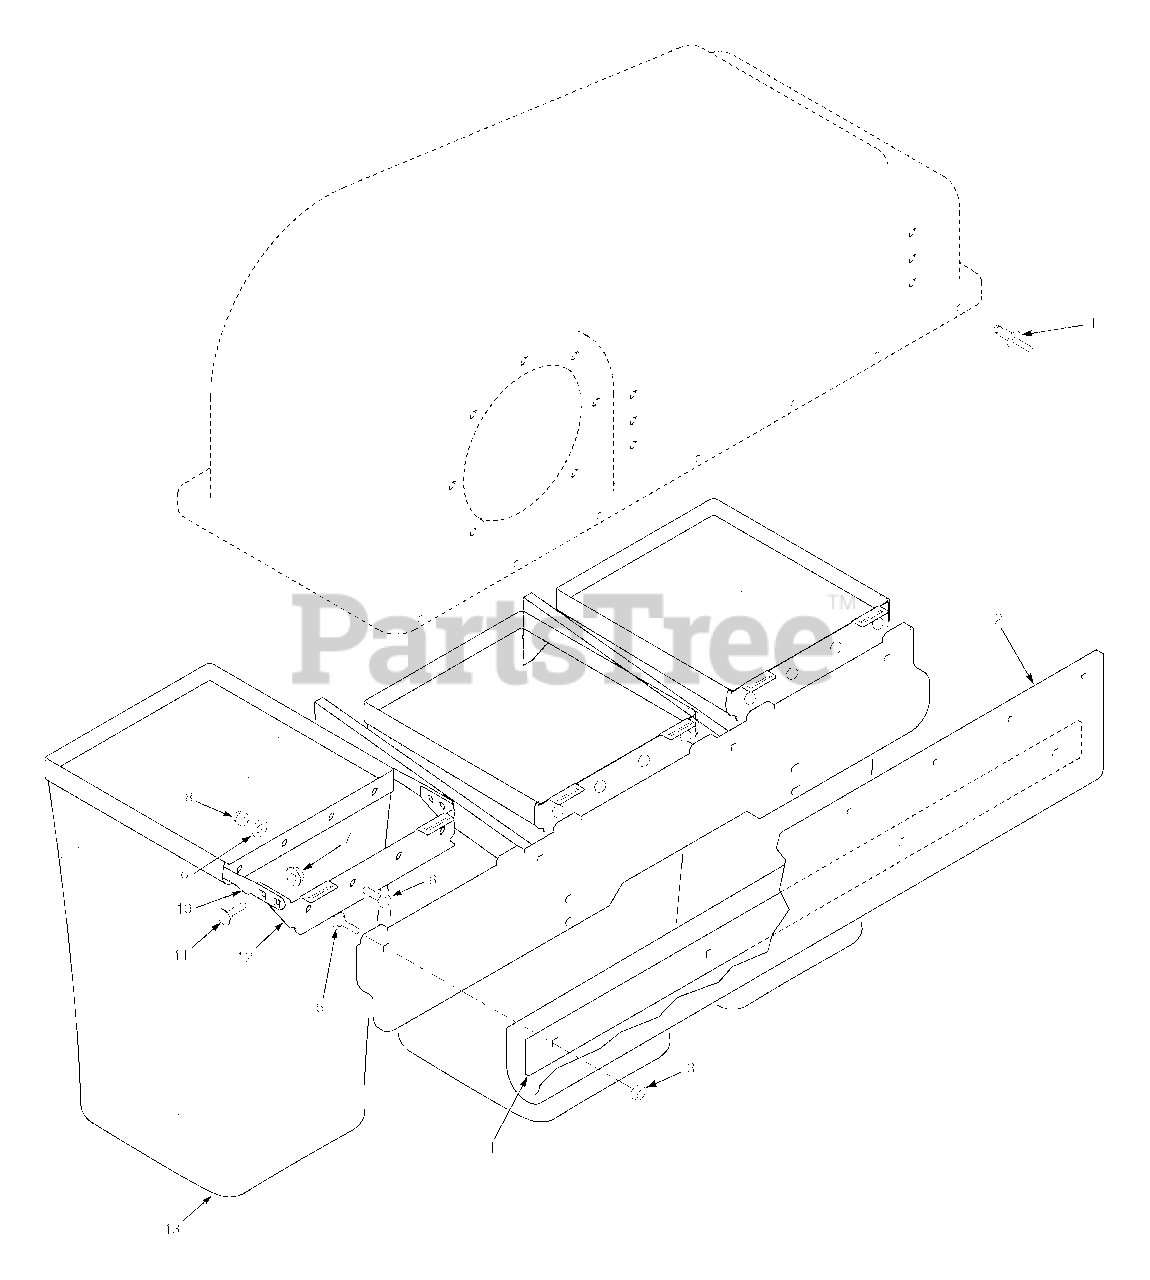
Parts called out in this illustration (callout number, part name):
1	Pop Rivet, 3/16 x .652
2	Seal, Hood
3	Lock Nut, 1/4-20 Center Lock
4	Retainer, Seal
5	Bolt, Carr. 1/4-20 x 3/4"
6	Bolt, Hex Head 5/16-18 x 3/4"
7	Nut, Serrated Flange 5/16-18
8	Nut, Elastic Stop 5/16-18
9	Flatwasher, 5/16-.375 x .875 x .083
10	Tube, Bag Support
11	Bolt, Carr. 5/16-18 x 3/4"
12	Mount, Bag Frame Tube
13	Bag Assembly, GC-STT
